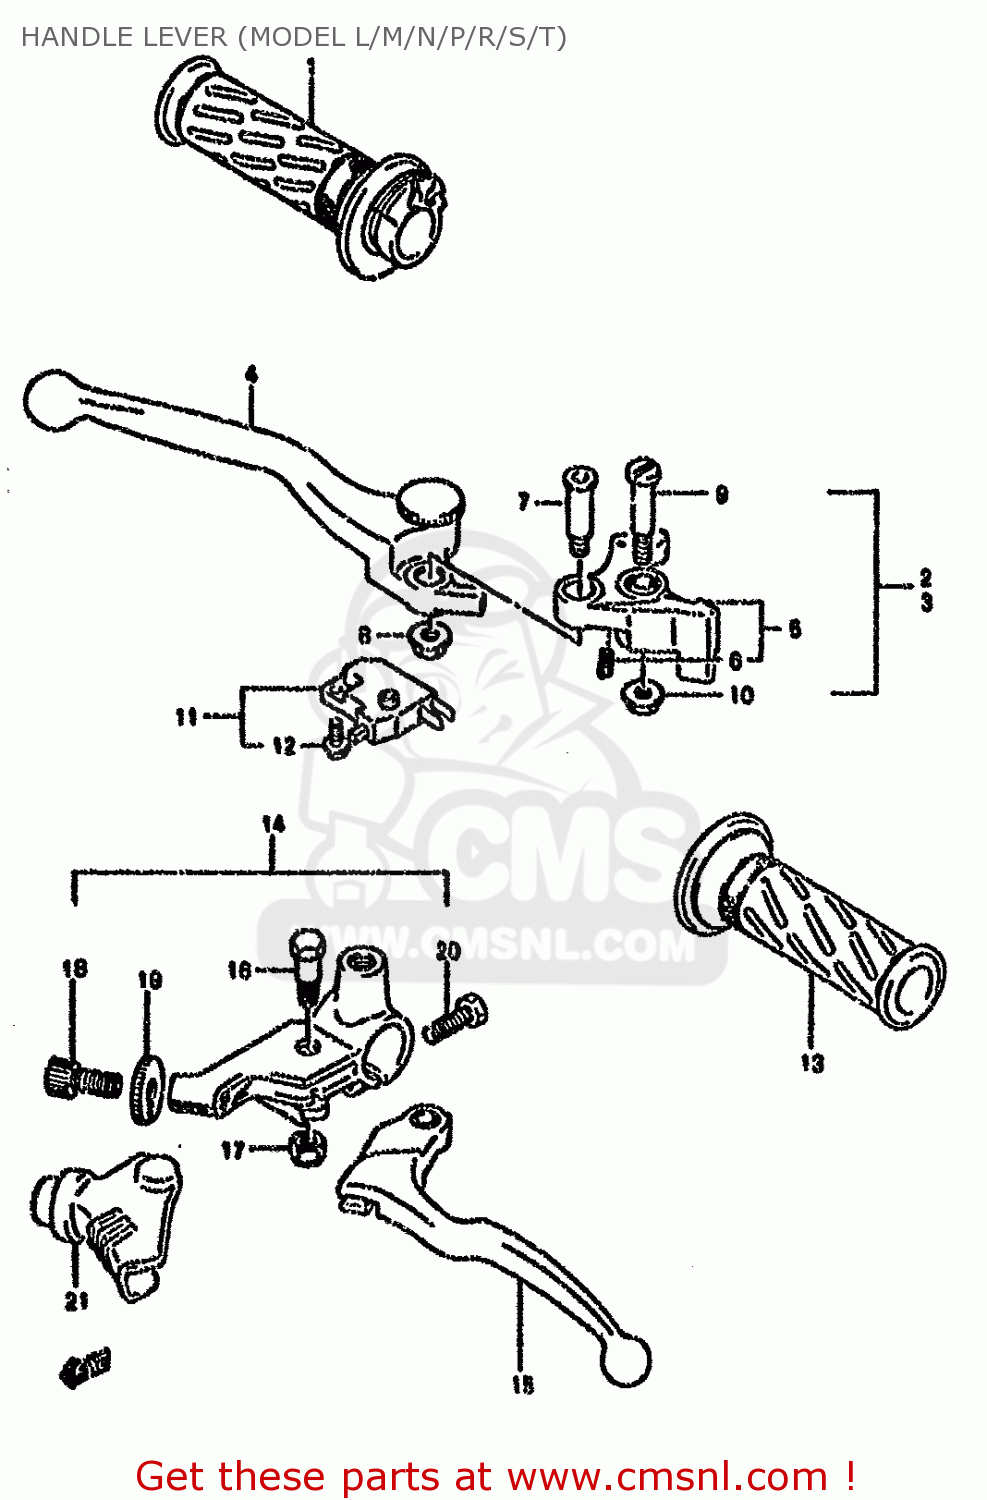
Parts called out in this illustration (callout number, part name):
1	GRIP,THROTTLE
2	LEVER ASSEMBLY,BRAKE
3	LEVER ASSEMBLY,BRAKE
4	LEVER,ADJUST
5	KNOCKER
6	SPRING
7	BOLT,LEVER
8	NUT
9	BOLT,LEVER PIVOT
10	NUT 6MM
11	SWITCH ASSEMBLY,STOP
12	SCREW
13	GRIP,L
14	LEVER ASSY,CLUTCH
15	LEVER,CLUTCH
16	BOLT,LEVER
17	NUT
18	ADJUSTER,CABLE
19	NUT,CABLE ADJUSTER
20	BOLT
21	COVER,CLUTCH LEVER
